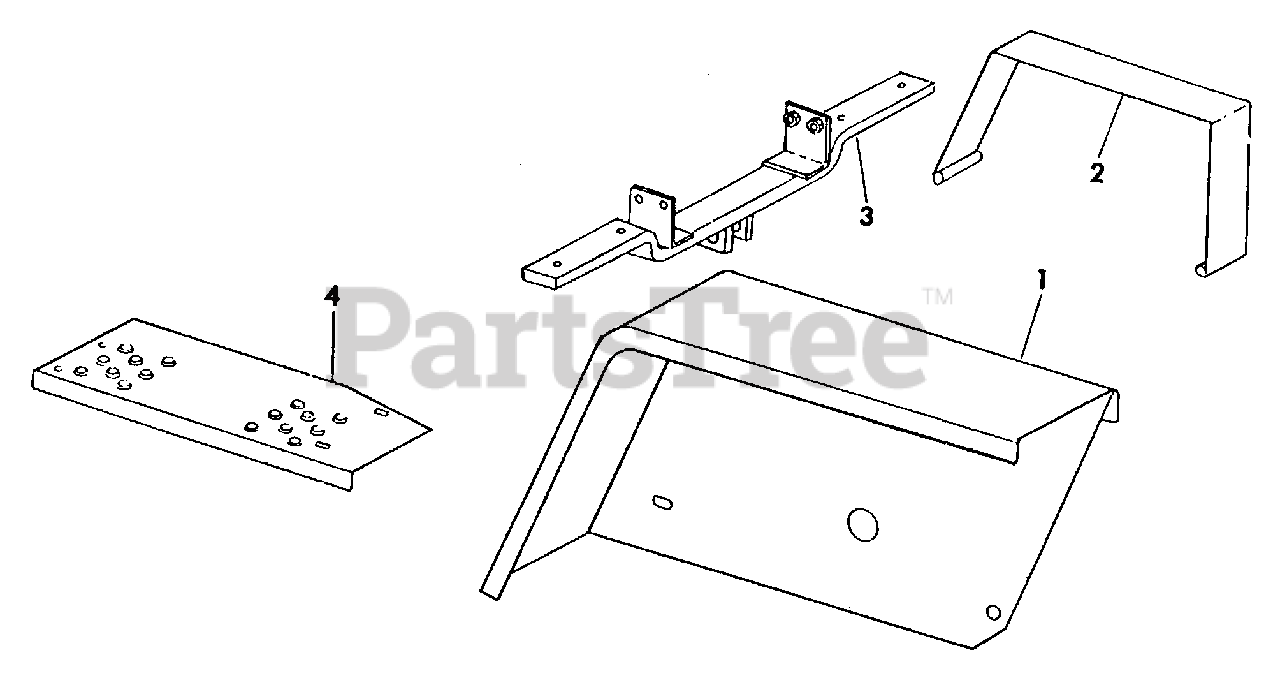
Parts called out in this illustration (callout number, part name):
1	Fender Assy, LH
3	Bar Assy, Foot Rest
4	Support, Foot LH
